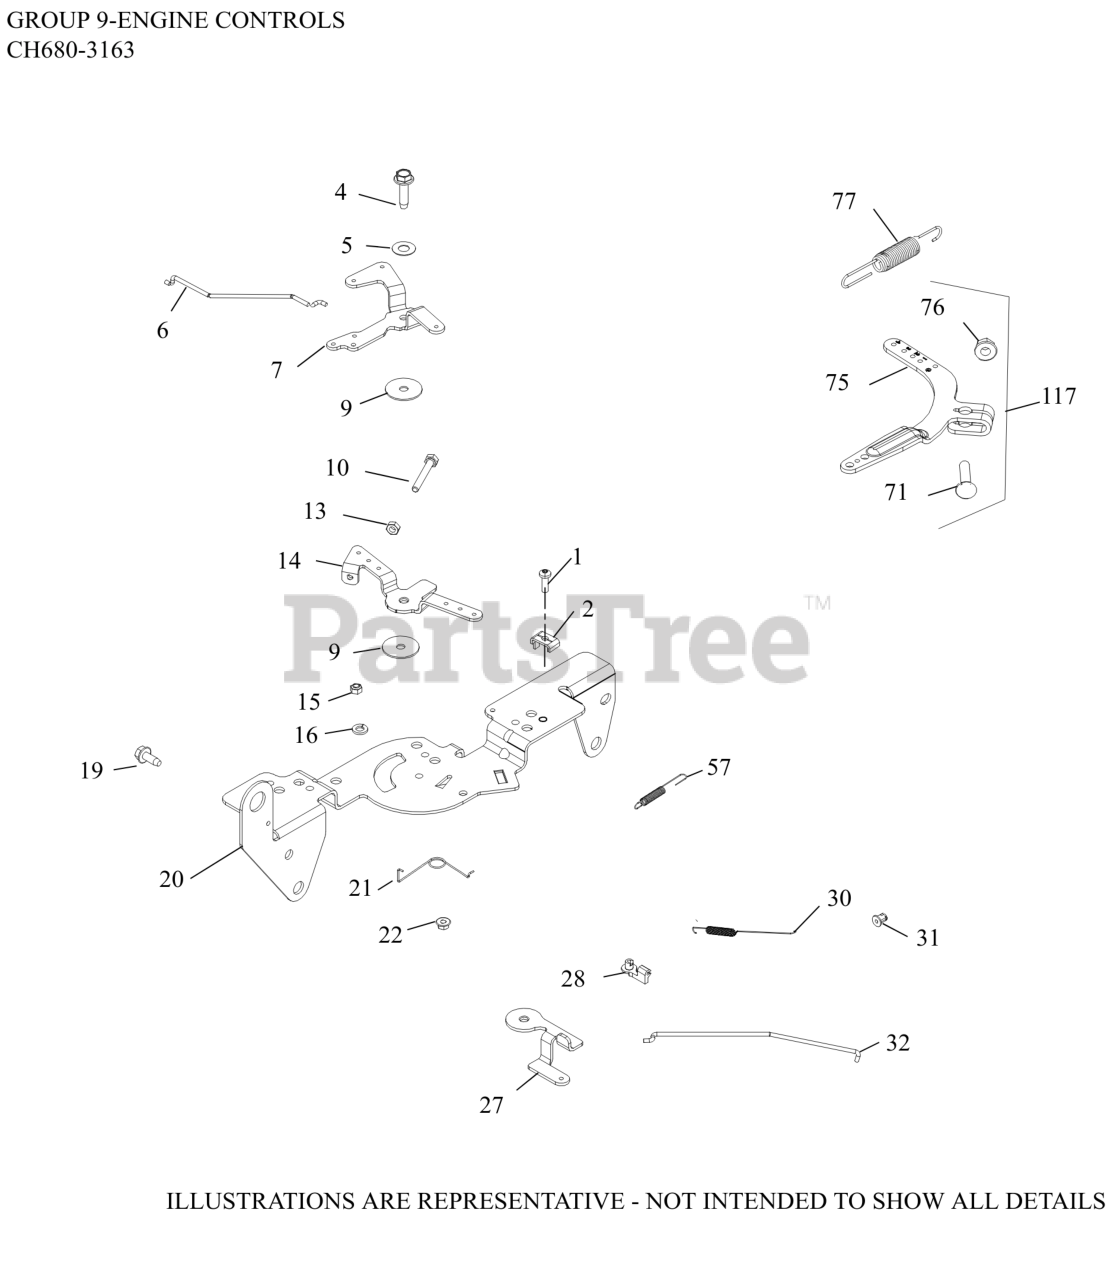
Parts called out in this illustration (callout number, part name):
1	SCREW, THREAD FORMING
2	CLAMP, CABLE CABLE
4	SCREW, THD FRM-USE 25 086 473-S
5	WASHER, SPRING 1/4"
6	LINKAGE, CHOKE
7	LEVER, CHOKE
9	WASHER, FLAT 5.5 MM
10	SCREW, CAP M4X.7X30
13	NUT, M4X0.7
14	LEVER, THROTTLE CONTROL
15	NUT, FLG M5X.8
16	WASHER, SPRING LOCK 1/4"
19	SCREW, THREAD FORMING
20	BRACKET, CONTROL
21	SPRING, CHOKE RETURN
22	NUT, LOCK M5X.8
27	LEVER, THROTTLE ACTUATOR
28	BUSHING, THROTTLE LINKAGE
30	SPRING, LINKAGE
31	BUSHING, LINKAGE RETAINING
32	LINKAGE, THROTTLE
57	SPRING, THROTTLE LIMITER
71	BOLT, RD HD SQ NECK M6X1.0X25
75	LEVER, GOVERNOR - (#2409069S)
76	NUT, FLG M6X1.0
77	SPRING, GOVERNOR (PURPLE)
117	LEVER, GOVERNOR ASSEMBLY
